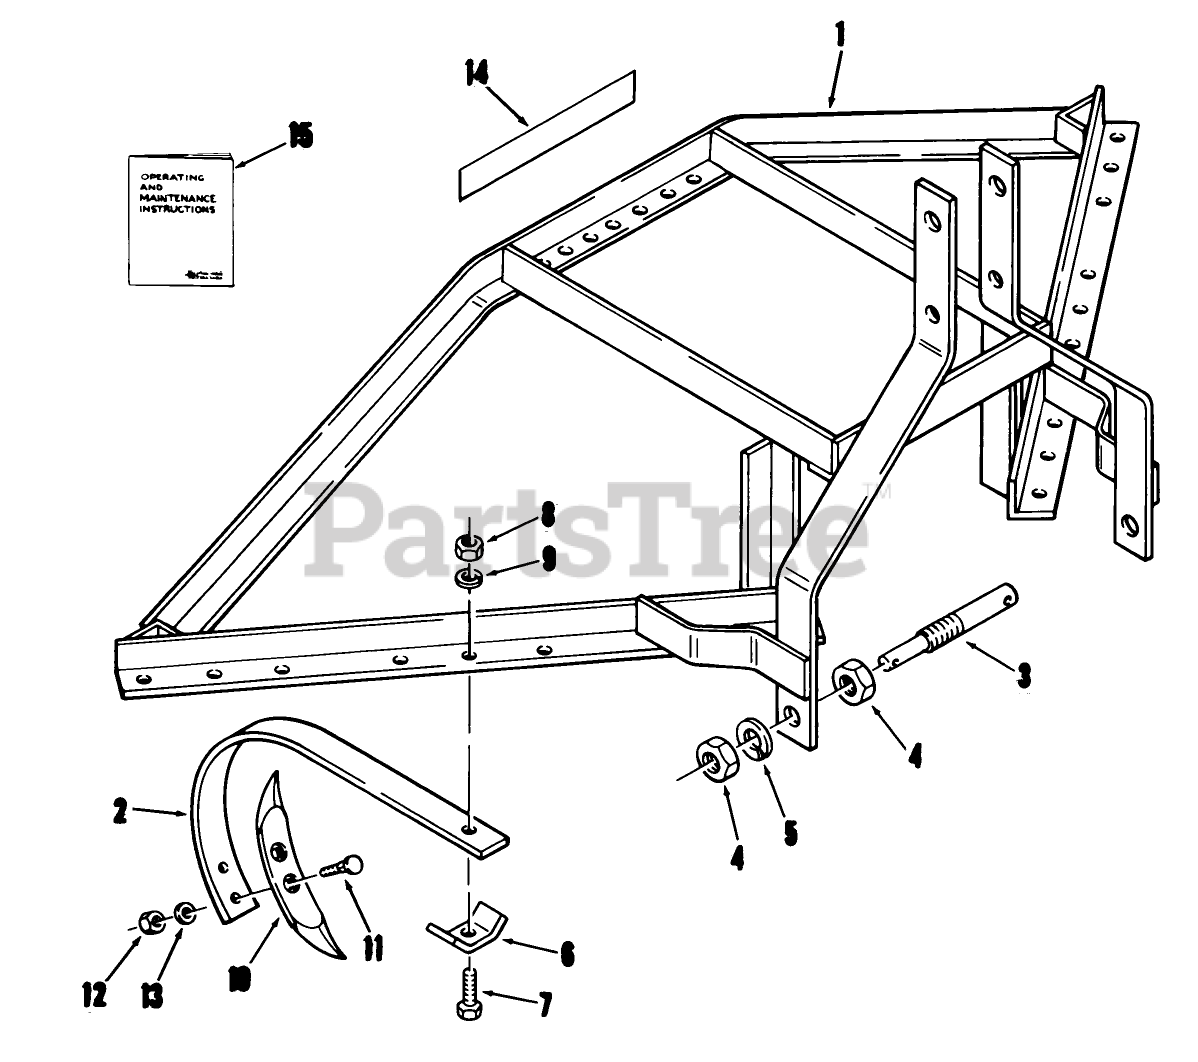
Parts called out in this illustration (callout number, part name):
1	Frame Assembly
2	Shank
3	Combination 5/8 7/8 Hitch Pin
4	Jam Nut 7/8-14
5	Lockwasher 7/8
6	Shank Clamp
10	Shovel
11	Plow Bolt 3/8-16 x 1
15	Operating and Maintenance Instructions
